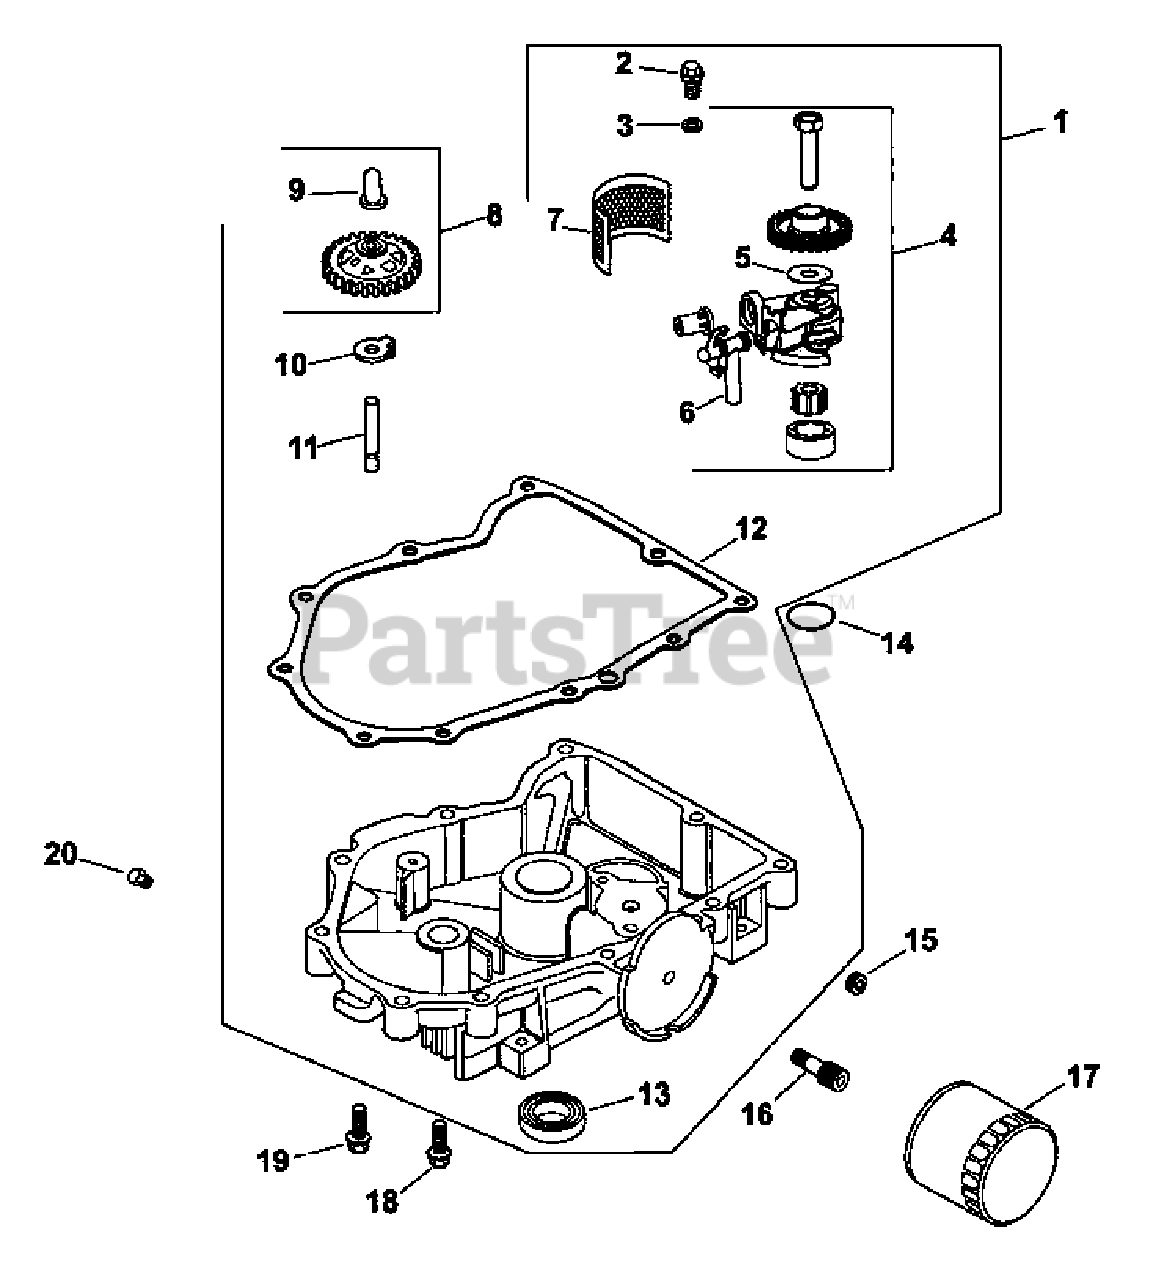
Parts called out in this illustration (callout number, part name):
1	Oil Pan w/Gasket Kit
2	Hex Flange Screw (M6 x 1.0 x 25)
3	Plain Washer 6mm
4	Oil Pump Assembly
6	Oil Pickup Tube
8	Governor Gear Kit
9	Governor Regulating Pin
11	Governor Gear Shaft
12	Oil Pan Gasket
13	Oil Seal (PTO End)
15	Hex Plug 3/8"
16	Oil Filter Nipple
17	Oil Filter
18	Hex Flange Screw (M8 x 1.25 x 45)
19	Hex Flange Screw (M8 x 1.25 x 45)
20	Plug, Pipe 3/8" Hex Head
